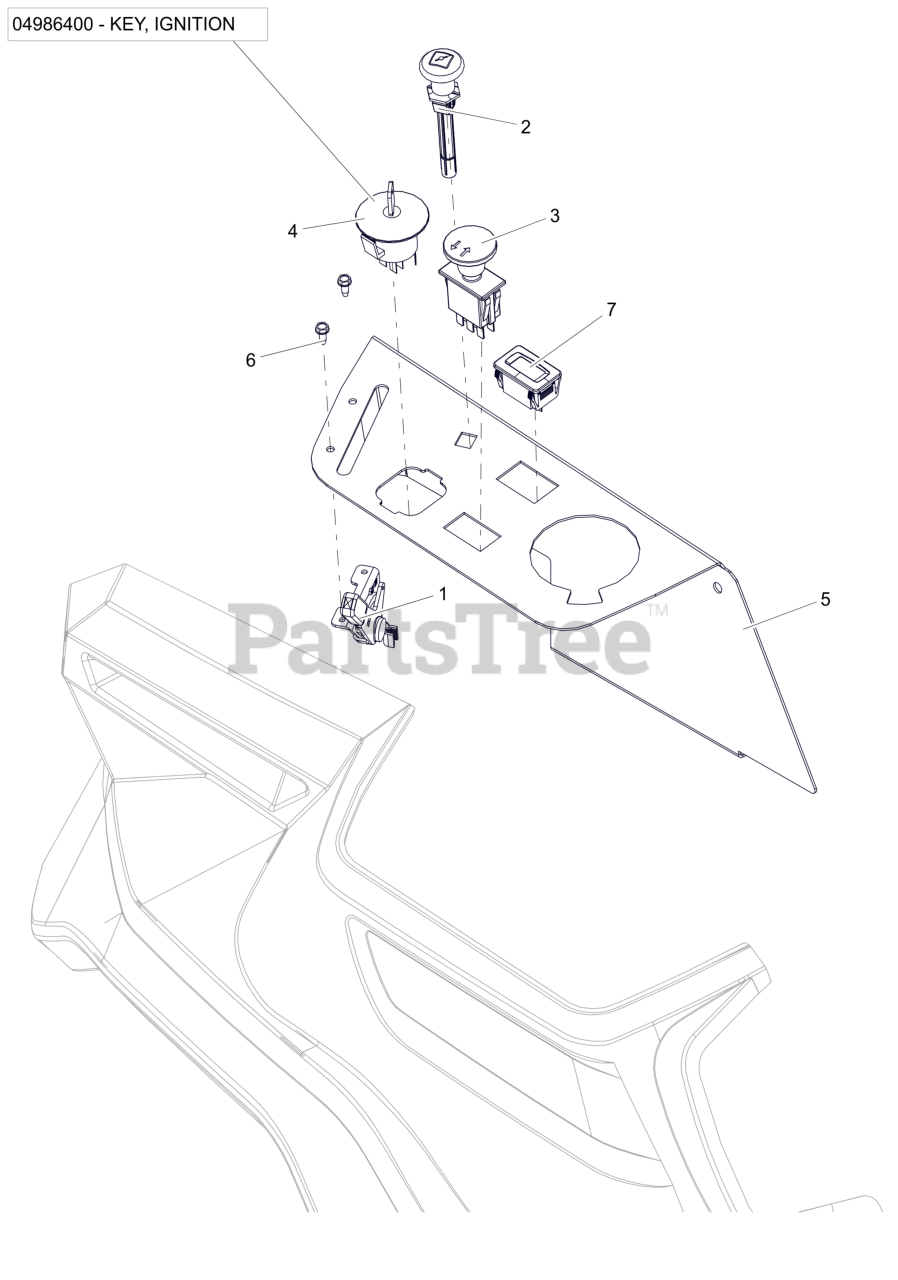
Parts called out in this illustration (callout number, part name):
1	CABLE - THROTTLE CONTROL
2	CABLE - CHOKE, SNAP-IN
3	SWITCH, CLUTCH (YELLOW)
4	KEYSWITCH-IGNITION 4 POS
4	KEY, IGNITION
5	PANEL, RIGHT SIDE FENDER MOUNT
6	SCR,TAP #10-24X.50 HWH TR ZCC
7	HOUR METER
